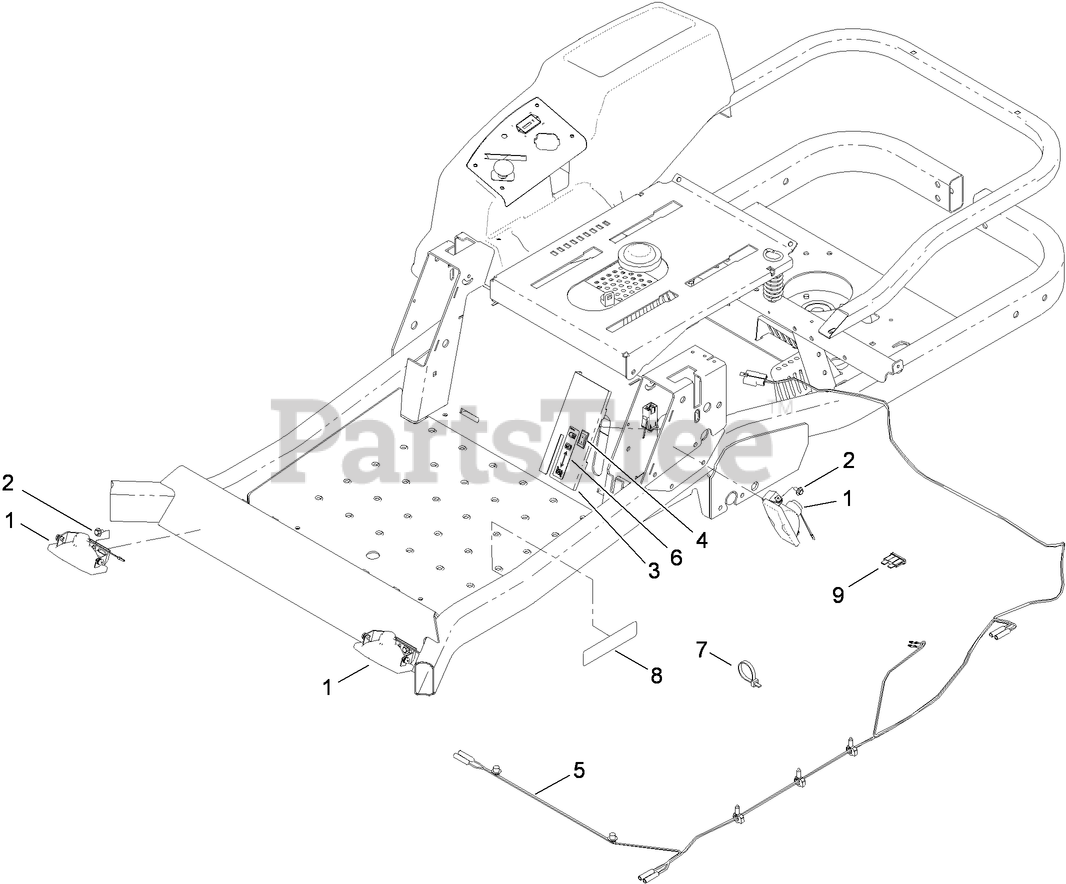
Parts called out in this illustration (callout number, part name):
1	LIGHT-HALOGEN, 35 WATT
2	SCREW-HHFTF
3	COVER-CONTROL, LH
4	SWITCH-ROCKER
5	HARNESS-WIRE
6	DECAL-LIGHT, PARKING BRAKE
7	TIE-CABLE
8	Decal-Clip
9	FUSE-BLADE, 15 AMP
